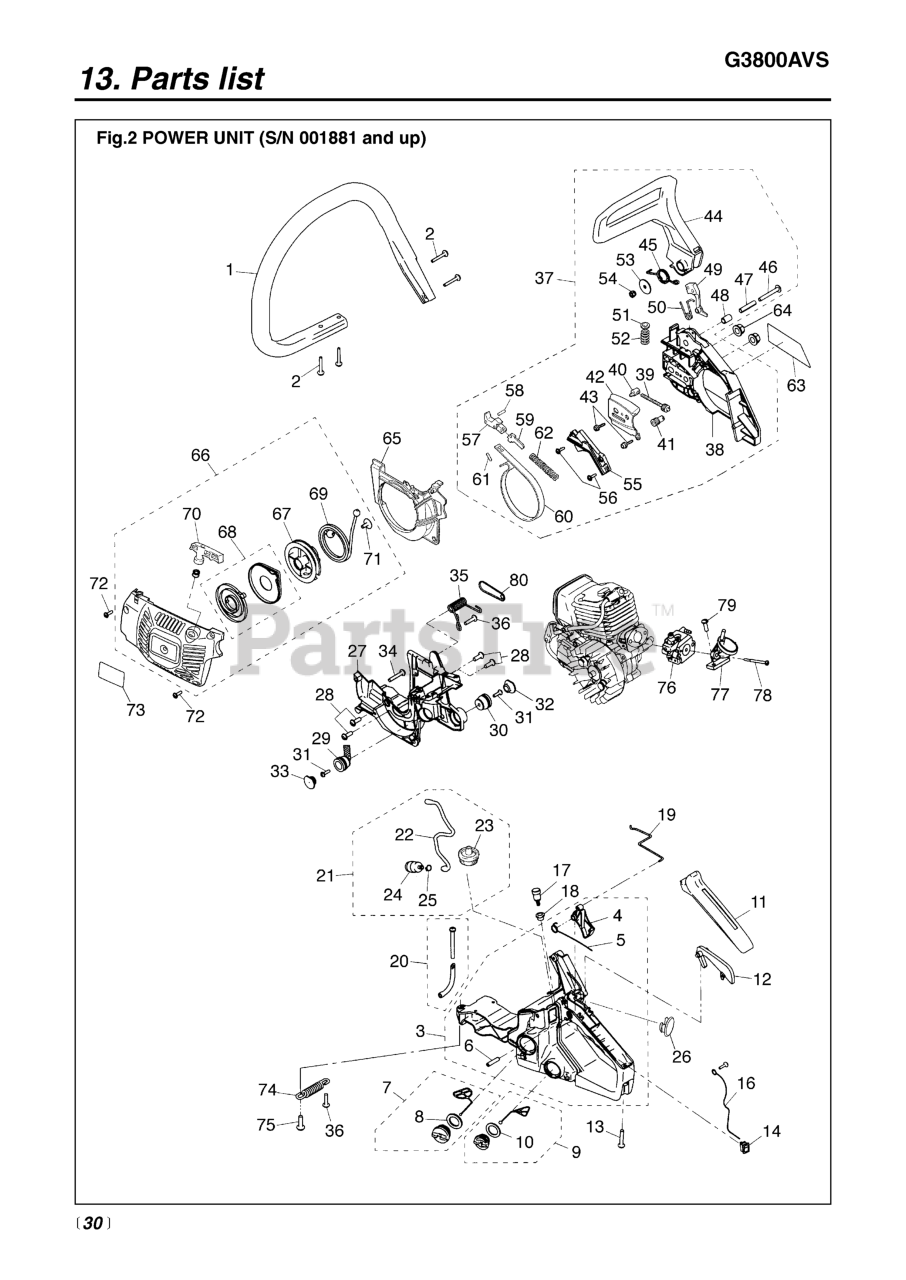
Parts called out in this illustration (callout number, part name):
1	HANDLE, LEFT
3	HANDLE, RIGHT ASSEMBLY
4	LEVER, THROTTLE
5	SPRING
7	CAP ASSEMBLY
8	GASKET
9	CAP ASSEMBLY
10	GASKET
11	COVER, GRIP
12	ARM (REPLACES 3356-33352)
14	SWITCH ASSEMBLY
16	CORD, SWITCH
17	BREATHER ASSEMBLY
18	GROMMET
19	ROD
20	PIPE COMPLETE
21	PIPE ASSEMBLY
22	PIPE, FUEL
24	5500-85400 (RRLS. 1750-85300)
25	CLIP (REPLACES 2841-31280)
26	CAP
27	CASE, ENGINE
28	SCREW (REPLACES 2616-24320)
29	DAMPER COMPLETE
30	DAMPER (RPLS 2670-35110)
31	SCREW
32	CAP
33	CAP
34	SCREW
35	SPRING, REAR
36	SCREW (RPLS. 2671-32110)
37	CHAIN BRAKE ASSY (RPLS-54003)
38	CHAIN COVER
39	SCREW
40	NUT
41	GEAR
42	PLATE, GUIDE
43	SCREW
44	GUARD, FRONT
45	SPRING, RETURN
48	SPACER (RPLS -54210)
49	WEIGHT
51	PLATE, STOPPER
53	WASHER (RPLS -75410)
54	NUT (B)
56	SCREW
57	LEVER, BRAKE COMPLETE
59	ARM, SLIDE(RPLS 2670-54410)
60	BAND, BRAKE
61	PIN
62	SPRING, BRAKE (RPLS. 50030121)
64	NUT
65	COVER, FAN
66	STARTER ASSEMBLY
67	REEL
68	SPRING
70	KNOB (RPLS -75420)
71	SCREW (RPLS -75150)
72	SCREW
74	SPRING, FRONT
75	SCREW (REPLACES 2616-24320)
76	CARBURETOR ASSY.
77	MANIFOLD
78	BOLT
79	SCREW
80	PLATE
